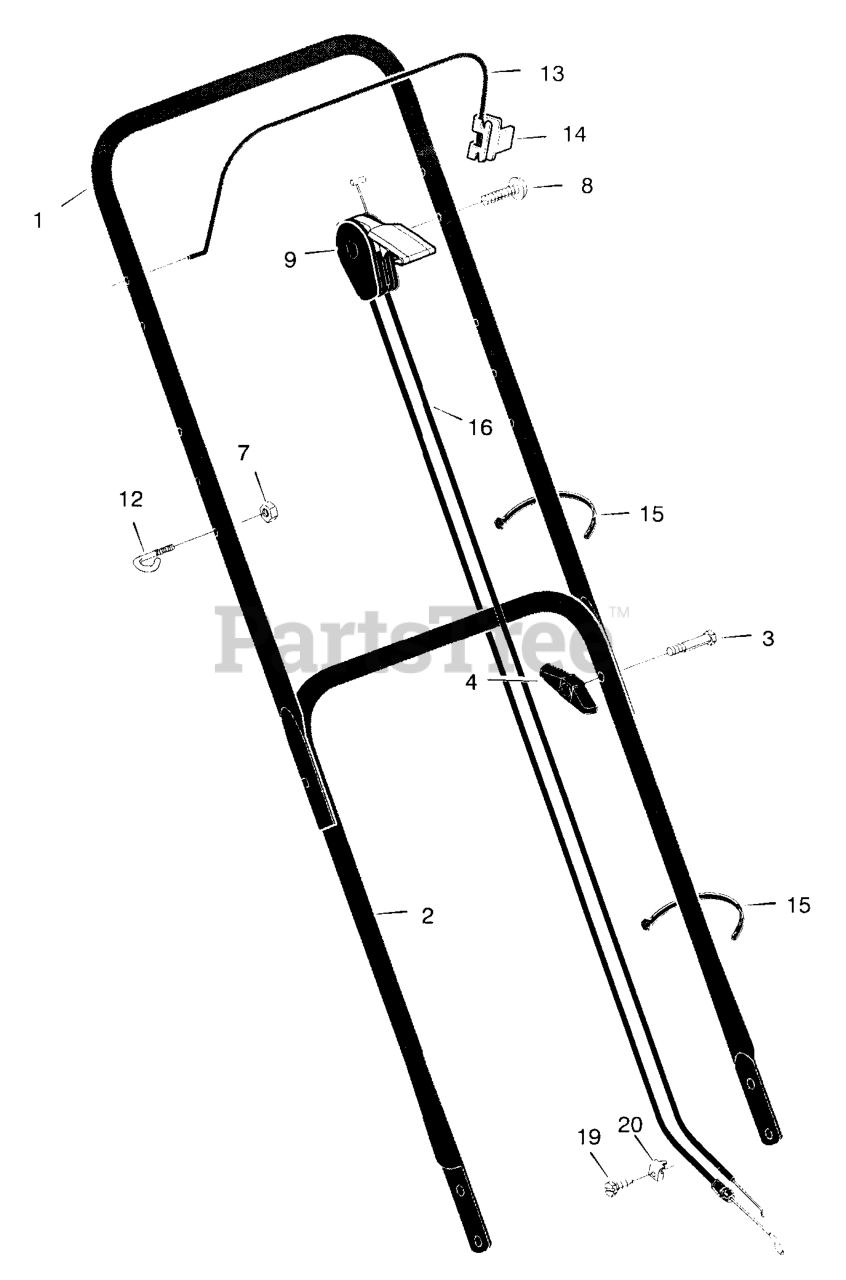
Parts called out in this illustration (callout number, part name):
1	Handle, Upper
2	Handle, Lower
4	Knob, Plastic
7	Locknut
9	Throttle Control
12	GUIDE, ROPE
13	Engine Stop Lever
14	Bracket, Stop Lever
15	Fastener, Cable
16	Engine Stop Cable
